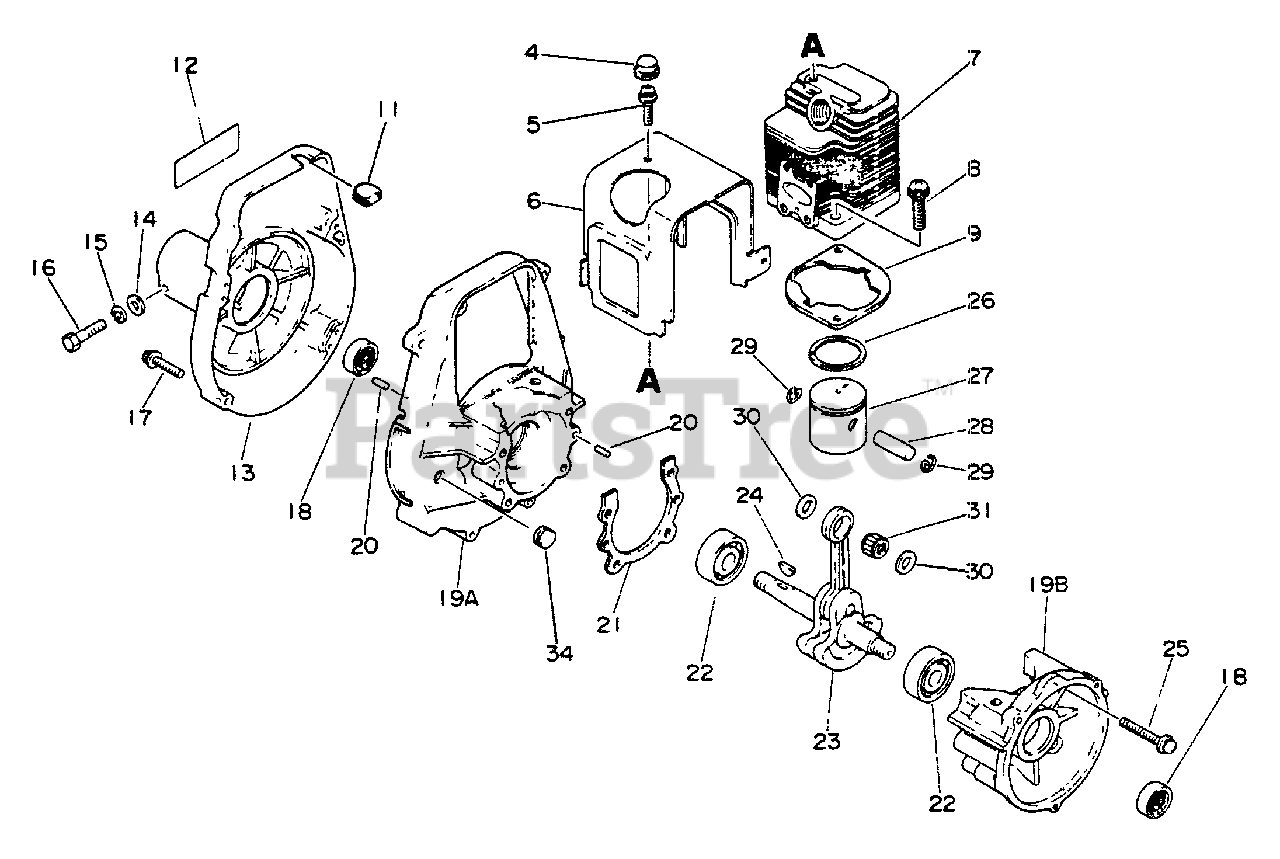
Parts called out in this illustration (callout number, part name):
4	SCREW - SOCKET HEAD CAP
5	SCREW 5×10
6	COVER, CYLINDER
7	CYLINDER
8	SCREW 6×20
9	GASKET, CYLINDER
11	PLUG
12	LABEL - MODEL
13	CASE, FAN
14	WASHER, FLAT 5.5×10×0.8
15	WASHER, SPRING 5
16	BOLT 5×25
17	SCREW 4×20
18	SEAL, OIL 12
19	CRANKCASE KIT
19A	CRANKCASE KIT
19B	CRANKCASE KIT
20	PIN, LOCATING 4
21	GASKET, CRANKCASE
22	BEARING, BALL - 6201 C3
23	CRANKSHAFT ASSY
25	SCREW 5×30
26	RING, PISTON
27	PISTON
28	PIN, PISTON
29	RING, SNAP
30	WASHER, THRUST
31	BEARING, NEEDLE
34	PLUG
